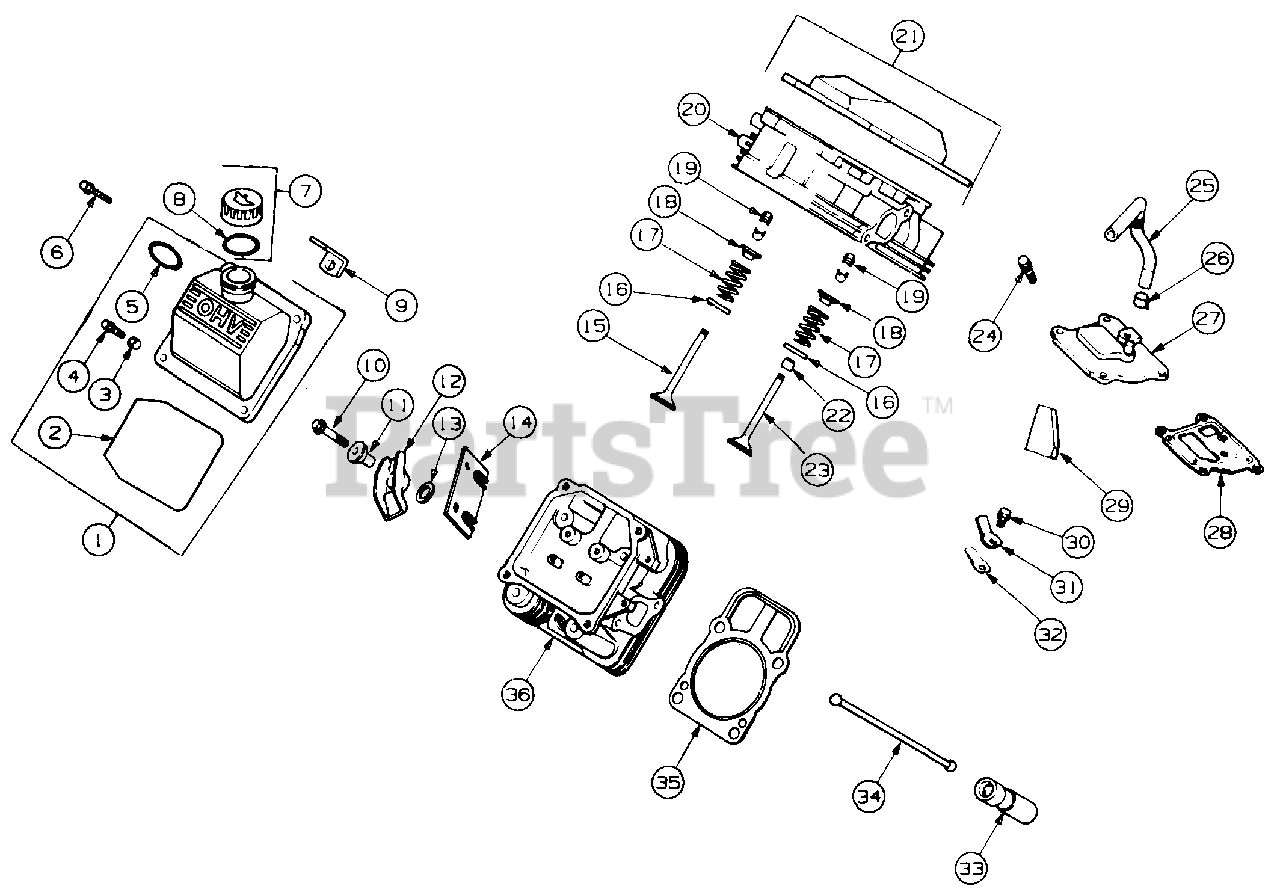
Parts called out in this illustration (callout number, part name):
1	Kit, Valve Cover w/Oil Fill
2	O-Ring, Cover
4	Screw, M6 X 1.0 X 30
5	O-Ring, Filler Neck
6	Screw, M10 X 1.5 X 91
7	Kit, Oil Fill Cap
8	O-Ring, Oil Fill Cap
9	Strap, Lifting
10	Screw, M6 X 1.0 X 34
11	Pivot, Rocker Arm
13	Washer, Flat
14	Plate, Guide
15	Valve, Exhaust, Std
16	Retainer, Spring
17	Spring, Valve
18	Cap, Valve Spring
19	Lock, Retainer
20	Head Assy, Cylinder #1
21	Kit, Valve Cover
22	Seal, Valve Stem
23	Valve, Intake, Std
24	Screw, M6 X 1.0 X 20
25	Hose, Breather
26	Clamp, Hose
27	Cover, Breather
28	Gasket, Breather
29	Filter, Breather
30	Screw, Breather Reed Retainer, M5 X 0.8 X 10
31	Retainer, Breather Reed
32	Reed, Breather
33	Lifter, Valve
34	Rod, Push
35	Gasket, Cylinder Head
36	Head Assy, Cylinder #2
